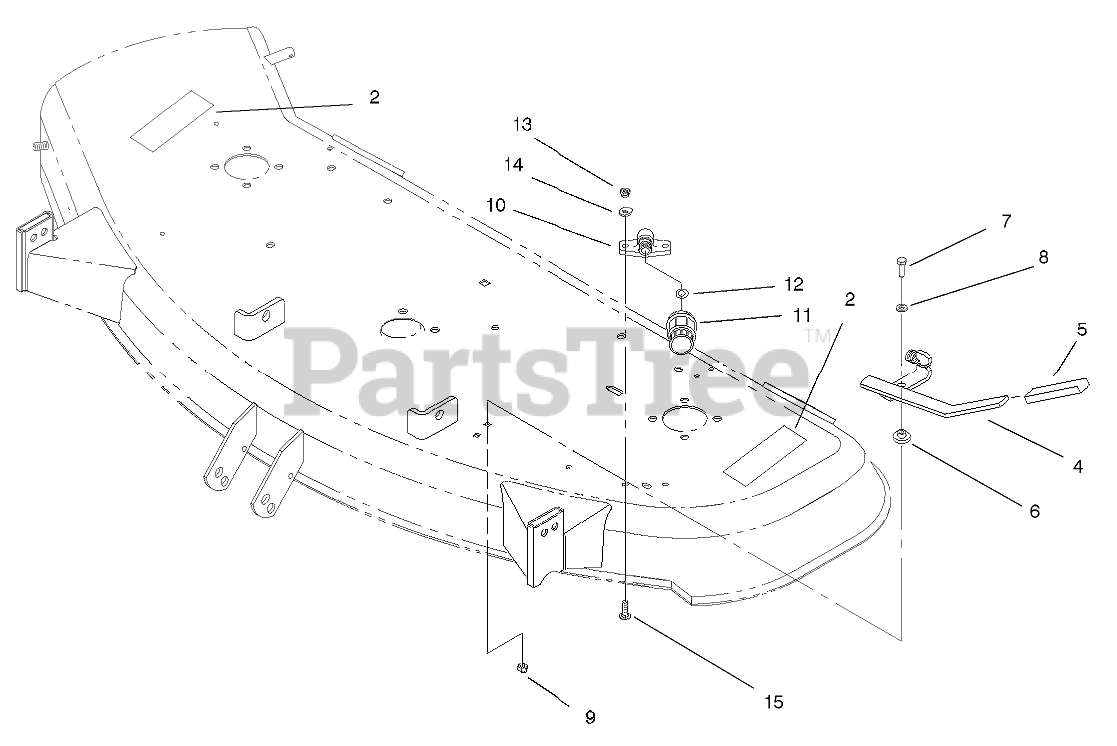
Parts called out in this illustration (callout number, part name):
2	DECAL-DANGER
6	SPACER-RACK, STEERING
7	SCREW-HH
8	WASHER-PLAIN
9	NUT-LOCK, NI
10	FITTING-WASHOUT
11	CONNECTOR-HOSE
12	O-RING
13	NUT-LOCK, NI
14	WASHER-FLAT
15	BOLT-CARR
